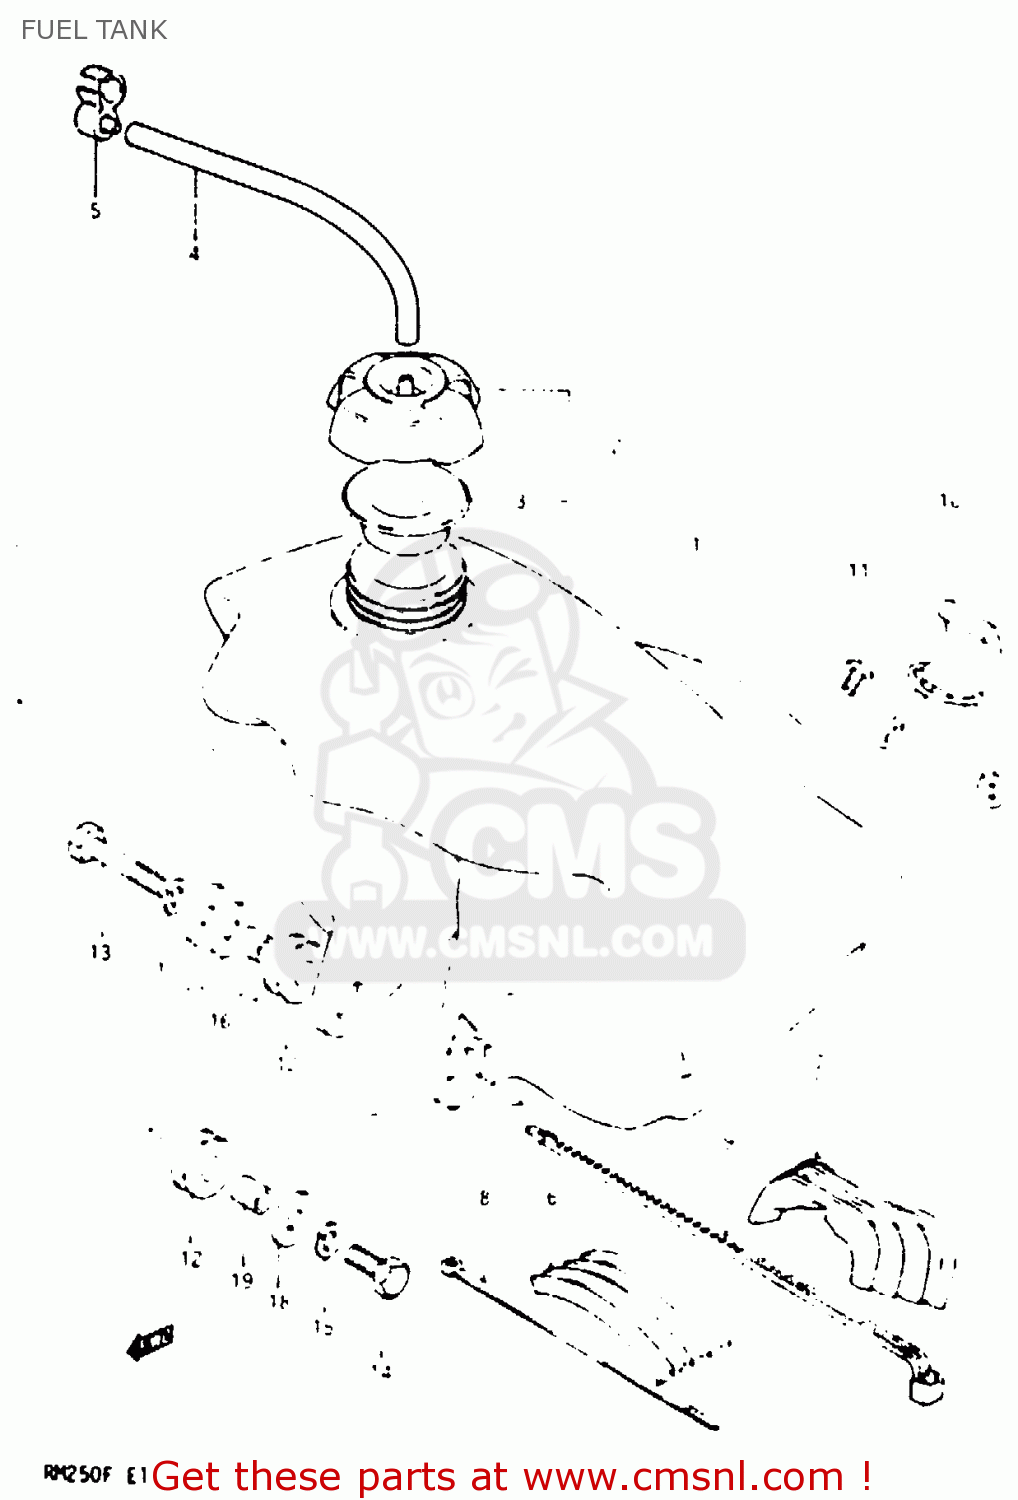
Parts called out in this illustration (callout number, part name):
1	TANK ASSEMBLY,FUEL
2	CAP SET,FUEL TANK
3	GASKET,FUEL TANK CAP (NAS)
4	HOSE
5	CLAMP,BREATHER HOSE
6	CUSHION,FUEL TANK UPR FR
7	CUSHION,FUEL TANK
8	CLAMP
9	CLAMP(L:250)
10	BAND,FUEL TANK RR
11	SCREW (6X15)
12	CUSHION
13	BOLT
14	BOLT
15	LOCK WASHER
16	WASHER
17	WASHER(8.5X26X1.2)
18	WASHER
19	SPACER (8.8X12X13.5)
